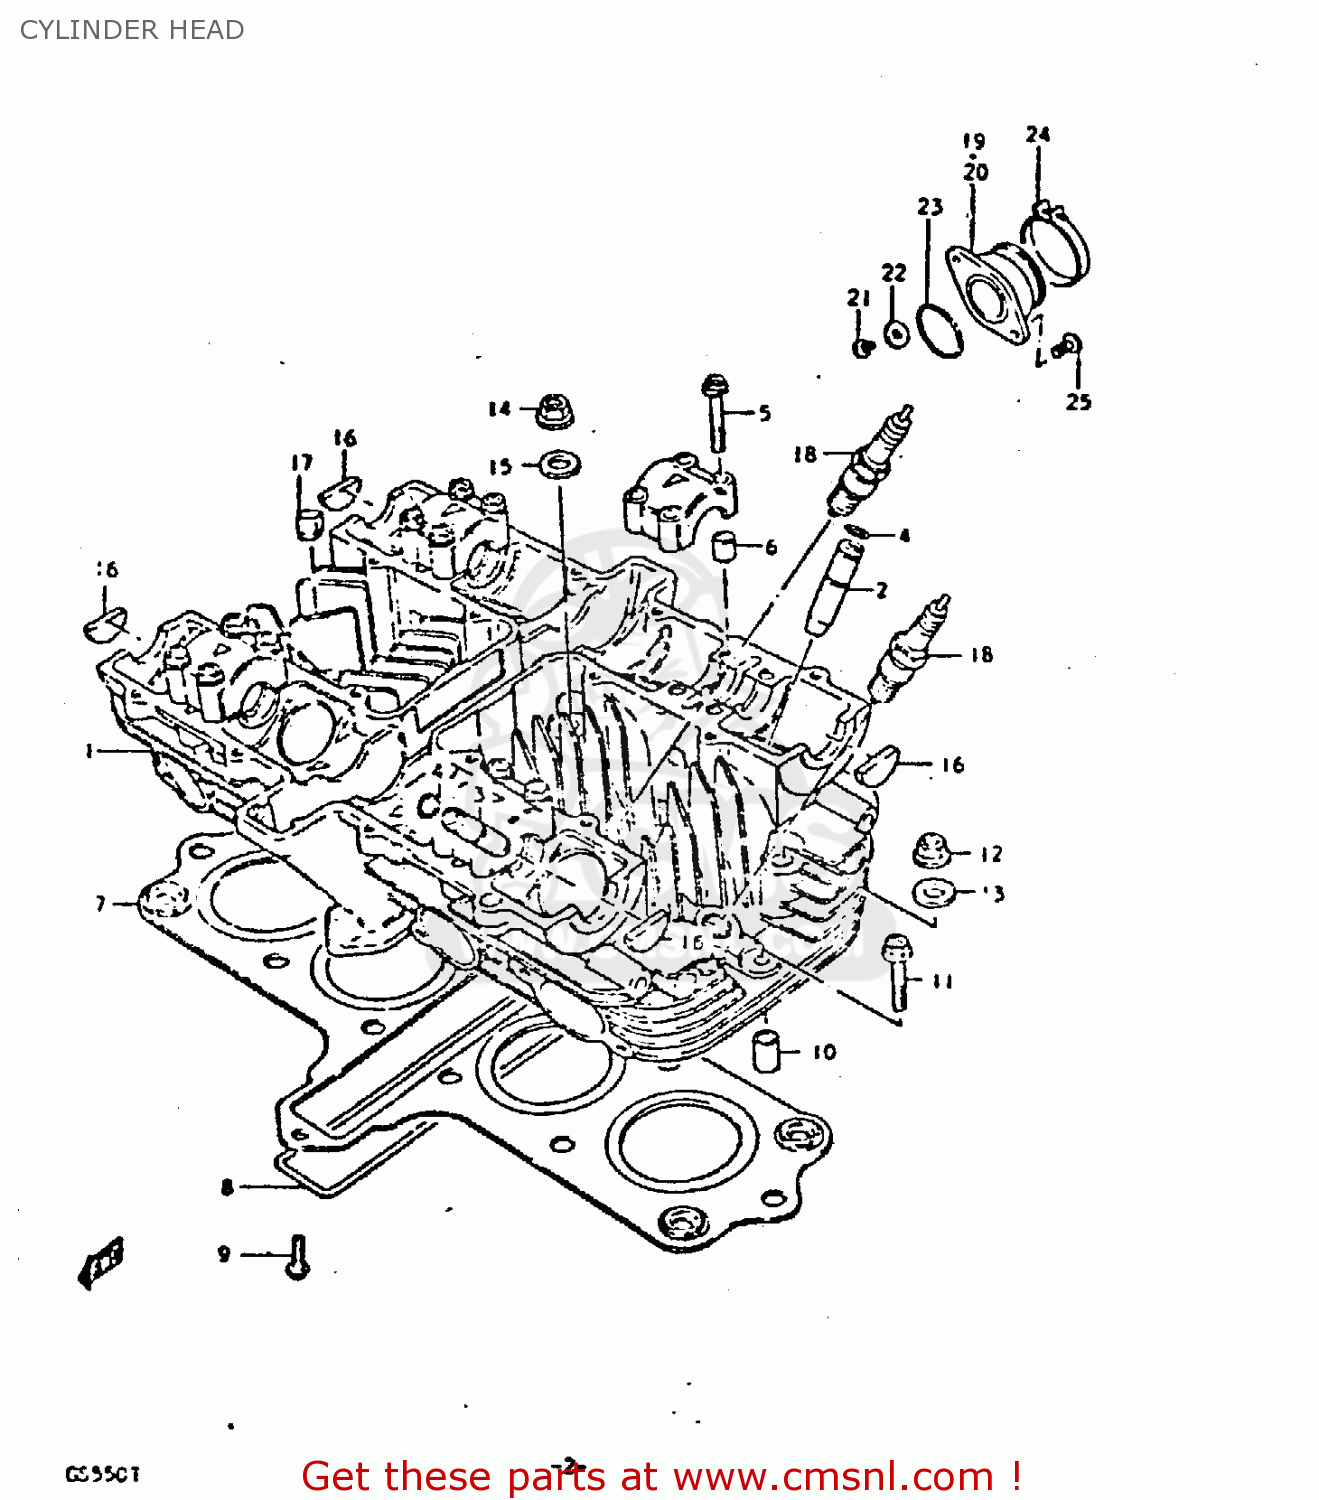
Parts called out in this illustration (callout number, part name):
1	HEAD ASSEMBLY,CYLINDER
2	GUIDE,VALVE
3	GUIDE,VALVE
4	RING,SNAP
5	BOLT(6X39)
6	PIN(6.2X8X11)
7	GASKET,CYLINDER HEAD (MCA)
8	O RING(D:3,ID:26X157)
9	BOLT
10	PIN
11	BOLT,UNDER
12	NUT
13	GASKET (NAS)
14	NUT
15	WASHER(8.5X19X2.3)
16	PLUG
17	PAD
18	SPARK PLUG
19	PIPE,INTAKE,R
20	PIPE,INTAKE,L
21	BOLT
22	WASHER
23	O-RING
24	CLAMP
25	SCREW
